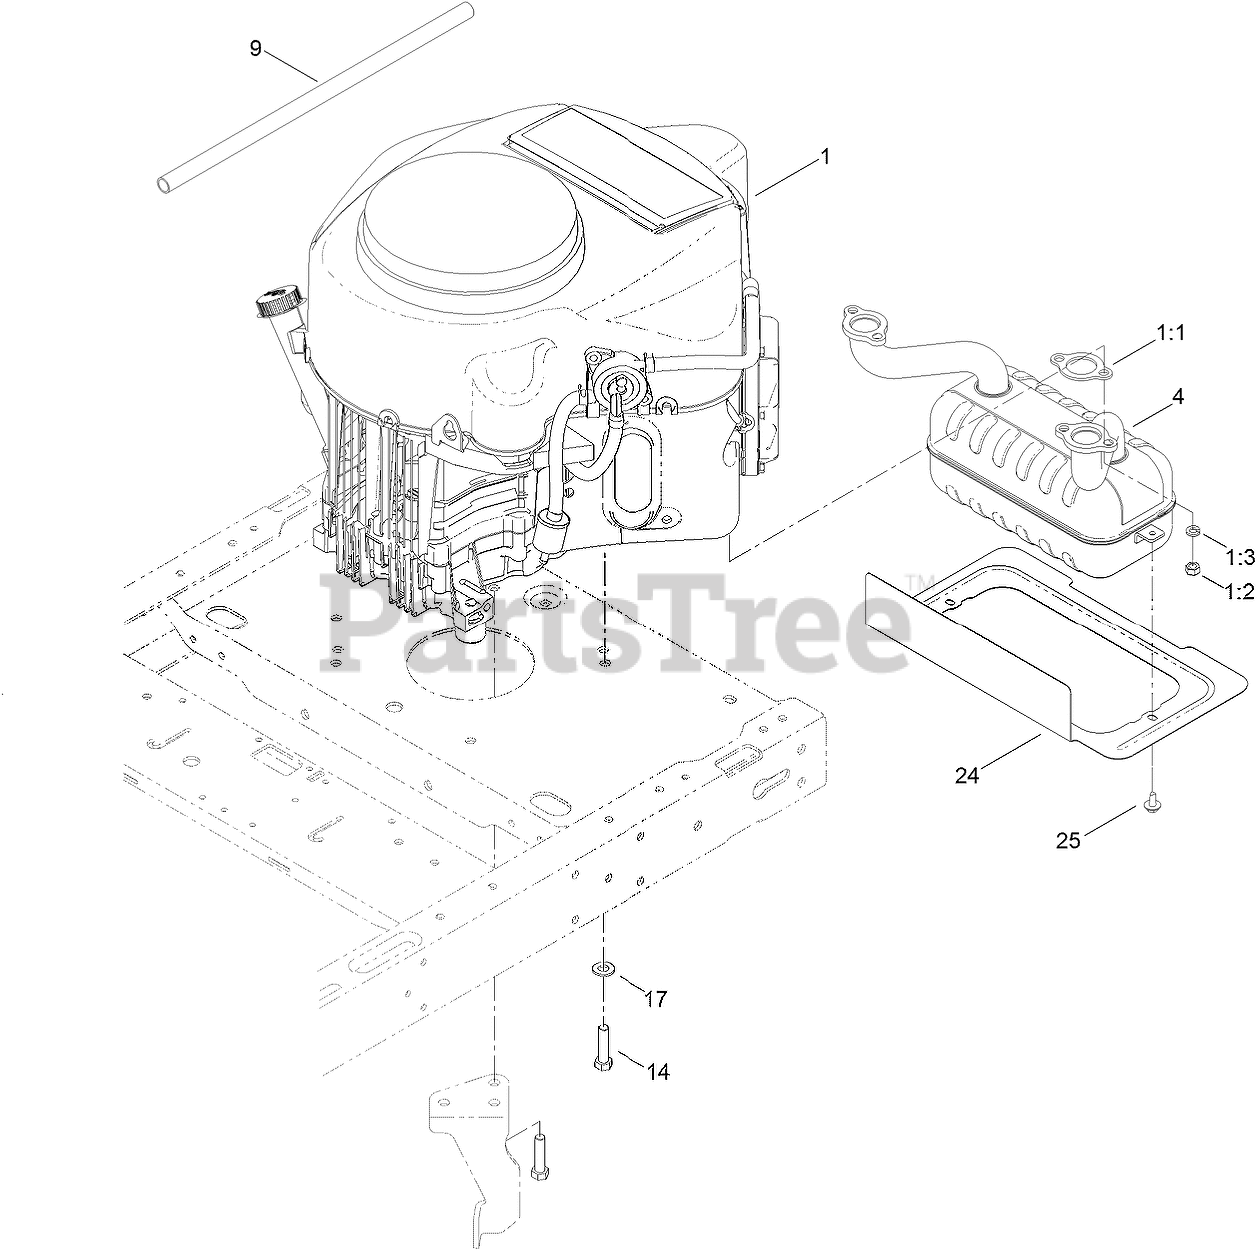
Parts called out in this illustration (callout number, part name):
1:1	GASKET-EXHAUST
1:3	WASHER-LOCK
4	MUFFLER-KAWASAKI
9	TUBE-DRAIN, OIL
14	BOLT-HH
17	WASHER-FLAT
24	SHIELD-HEAT
25	SCREW-HHFTF
